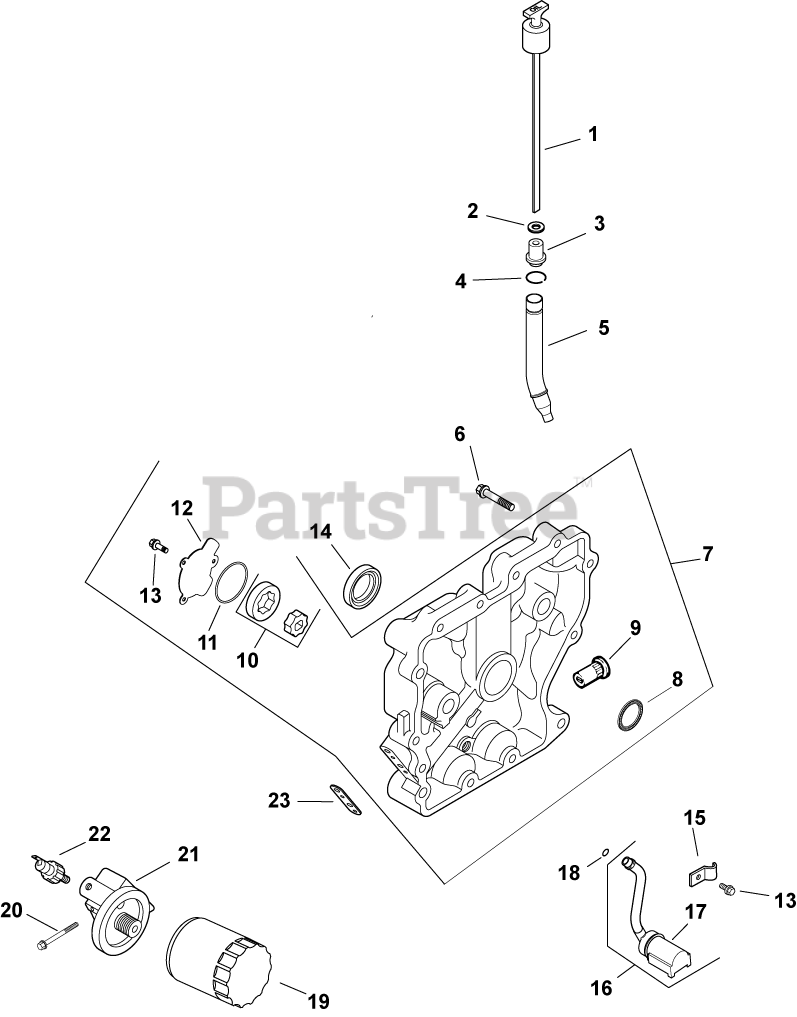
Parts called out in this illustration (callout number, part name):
3	SEAL USE 25 032 13-S
5	TUBE, OIL FILL
6	SCREW, FLG M8X1.25X45
7	CLOSURE PLATE ASSEMBLY - DISCONTINUED
8	BEARING, CRANKSHAFT
9	VALVE, OIL PRESSURE RELIEF
10	PUMP ASSEMBLY, OIL
11	O-RING (1.78" DIA)
12	COVER, OIL PUMP
13	SCREW,FLG THD FRM M5X0.8X16-(#25086398S)
14	SEAL, OIL
16	KIT, OIL PICK-UP
17	PICK-UP, OIL SCREEN
18	O-RING (.5" DIA)
19	OIL FILTER
20	SCREW, FLG M6X1.0X60
21	ADAPTER - DISCONTINUED
22	SENSOR, OIL PSI
23	GASKET, OIL FILTER ADAPTER
